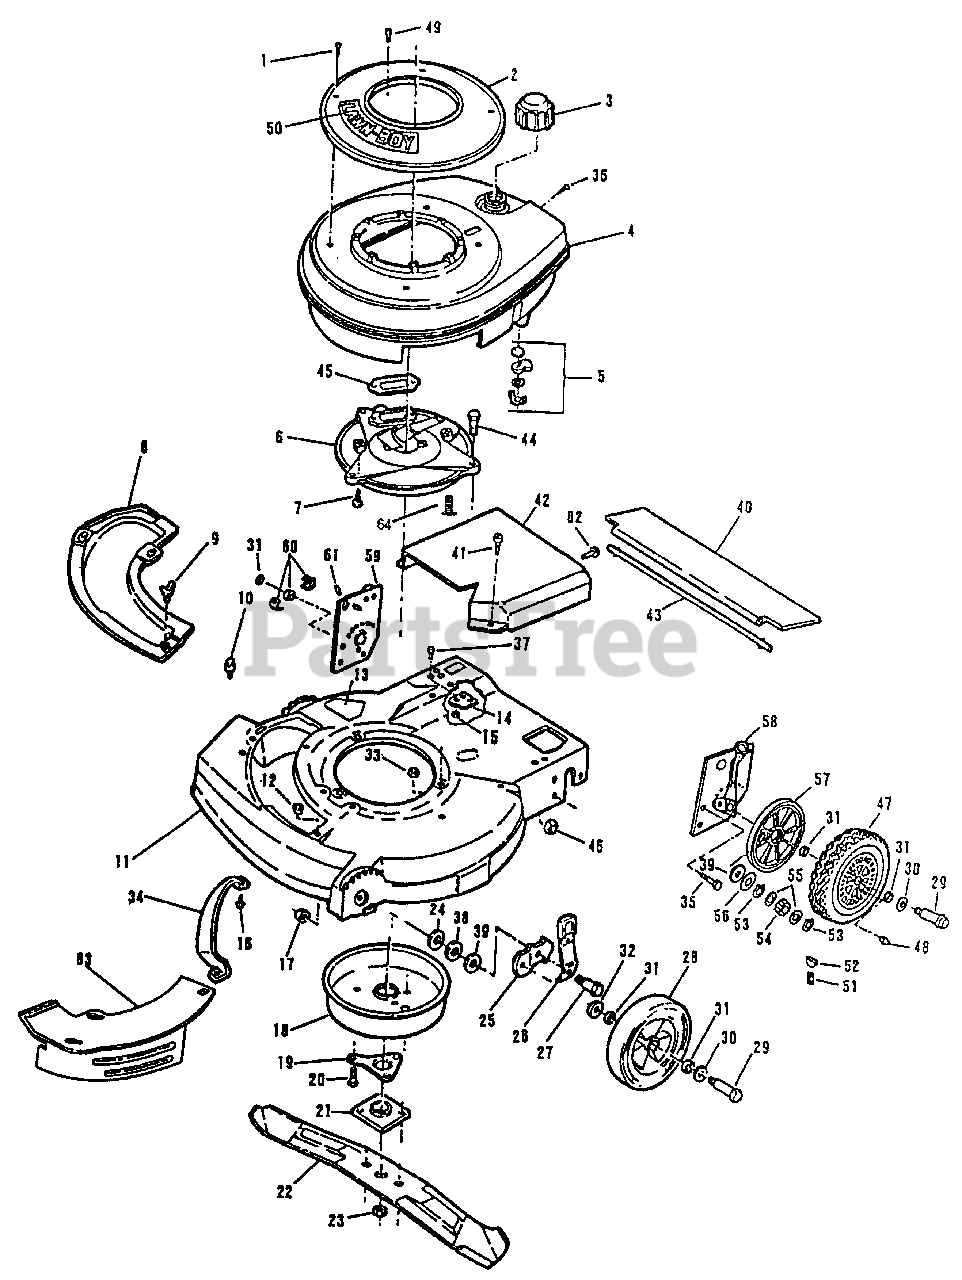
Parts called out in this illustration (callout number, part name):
1	Screw
2	Starter Base and Nut Assembly
3	Fuel Cap
4	Shroud-Engine
5	Fuel Shut-Off Assembly
6	Plate Muffler
7	Screw-Muffler Plate to Block
8	Cover Plate
9	Wing Screw
10	Screw-Plate and Chute Mounting
11	Housing Assembly
12	Grommet
13	Decal-Blade Contact Warning
14	Bolster-Housing
15	Nut-Bolster to Housing
16	Screw
17	Nut
18	Muffler Cover Assembly
19	Support-Crankshaft
20	Screw-Muffler to Muffler Plate
21	Collar and Plate Assembly
22	Blade-21"
23	Nut-Blade
24	Washer
25	Bracket-Wheel Height Adjust
26	Knob and Spring Assembly
27	Bolt-Shoulder
28	Wheel-Front
29	Bolt-Wheel
30	Washer-Felt
31	Washer-Felt
32	Washer
33	Nut-Muffler Plate to Housing
34	Toe Bar
35	Screw-Handle Bracket
36	Screw-Shroud to C.D. Bracket
37	Screw-Bolster to Housing
38	Washer Shim-Wheel Height Adjust Bracket
39	Washer-Shim-Wheel Height Adjust Bracket
40	Shield-Trailing
41	Screw-Drive Cover Mounting
42	Cover-Drive
43	Rod-Trailing Shield
44	Screw-Muffler Plate to Housing
45	Gasket-Exhaust
46	Locknut-Hdl. Brkt. to Housing
47	Rear Wheel
48	Lube Fitting
49	Screw-Starter Mounting
50	Applique-Starter Base
51	Spring
52	Key
53	Retaining Ring
54	Pinion
55	Spacer
56	Washer
57	Cover-Rear Wheel
58	Height Adjuster Assembly-L.H.
59	Height Adjuster Assembly-R.H.
60	Bearing and Retainer Assembly
61	Fitting
62	Screw
63	Mulcher Plate Kit w/Decal
64	Screw-Muffler Plate To Block
